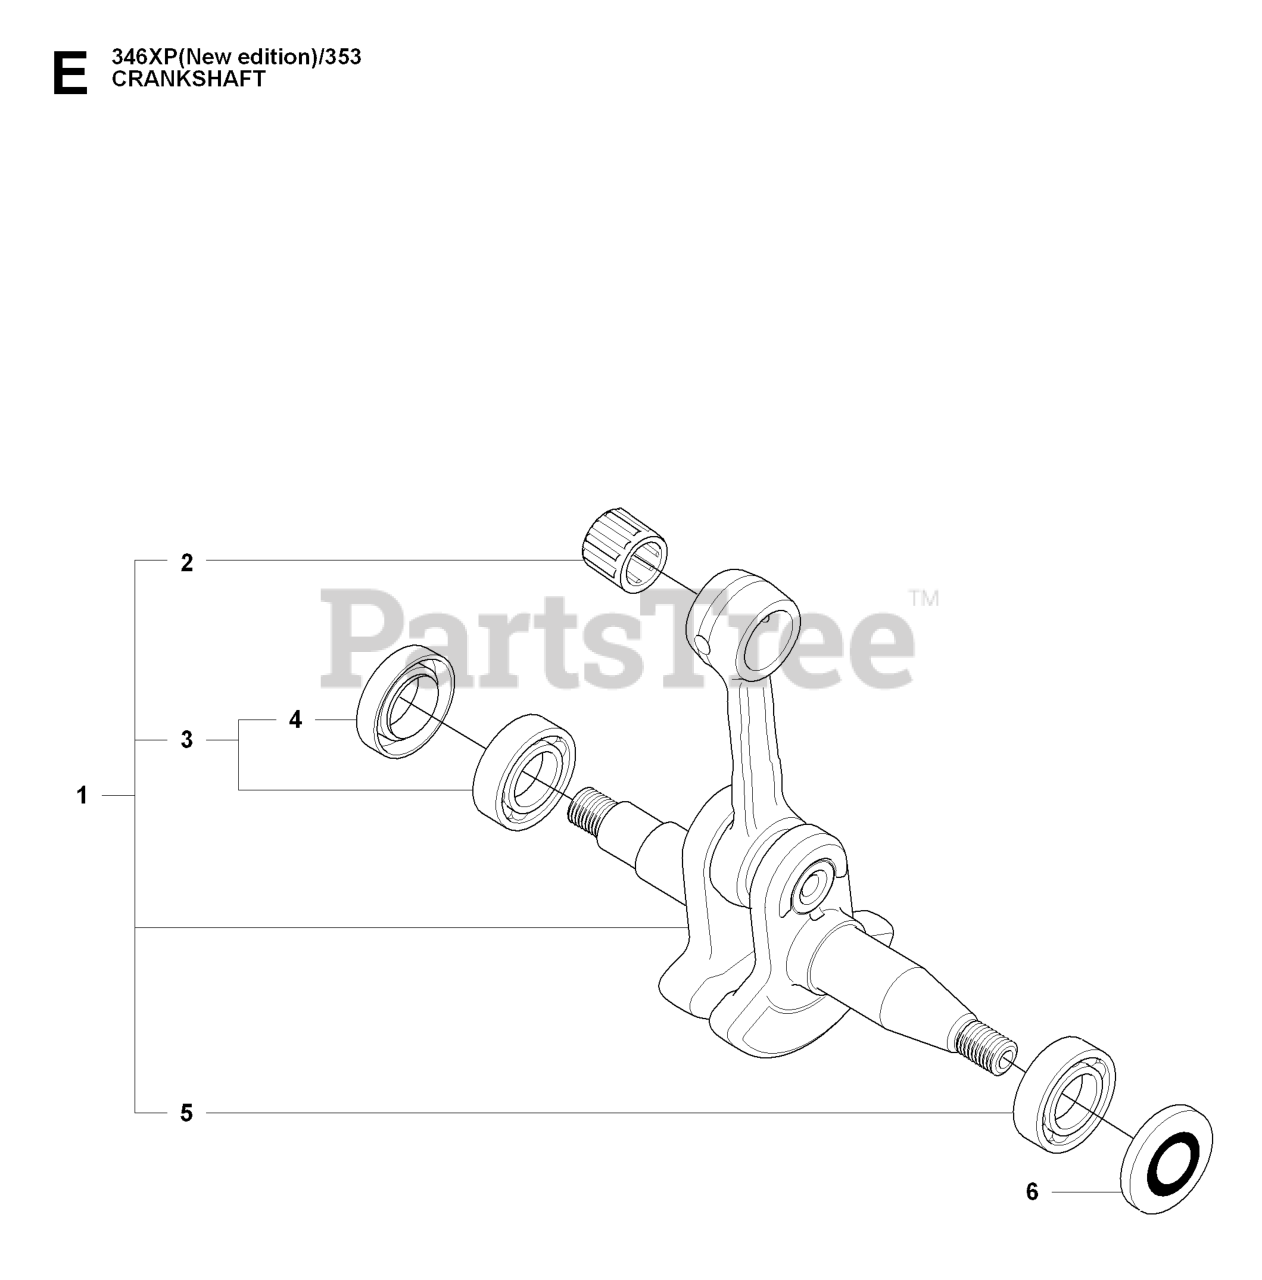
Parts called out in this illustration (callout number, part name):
1	%CRANKSHAFT
2	SUPPORT BUSHING
3	%BALL BEARING
4	RADIAL SEAL
5	BALL BEARING-6202-C3 SKF
